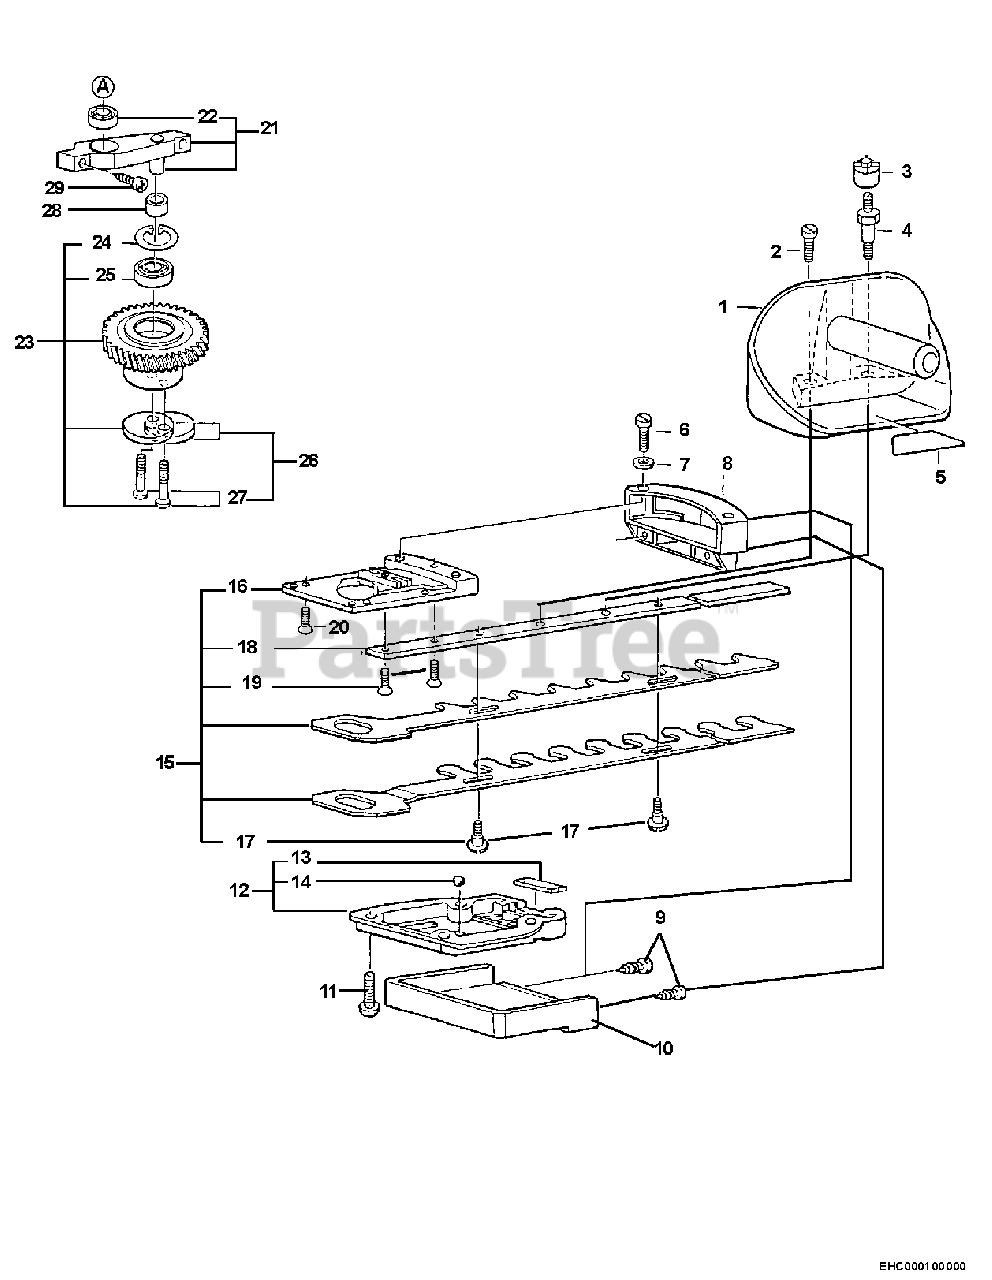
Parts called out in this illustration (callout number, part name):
1	HANDLE, AUX.
2	SCREW
3	NUT
4	DBL. END BOLT
5	LABEL - CAUTION
7	LOCKWASHER
9	SCREW - 4X16
11	SCREW - 4X22
12	LID, GEAR CASE
13	SEAL, FELT
14	BALL - 4
15	BLADE ASSY - 770mm
16	FLANGE
17	SCREW
18	BAR, FRAME 770MM
20	SCREW
21	BEARING FLANGE ASSY
22	BEARING, BALL
23	GEAR ASSY
24	RING, RETAINING
25	BEARING, BALL
26	PLATE ASSY
27	DRIVING PIN
28	SPACER
29	SCREW
